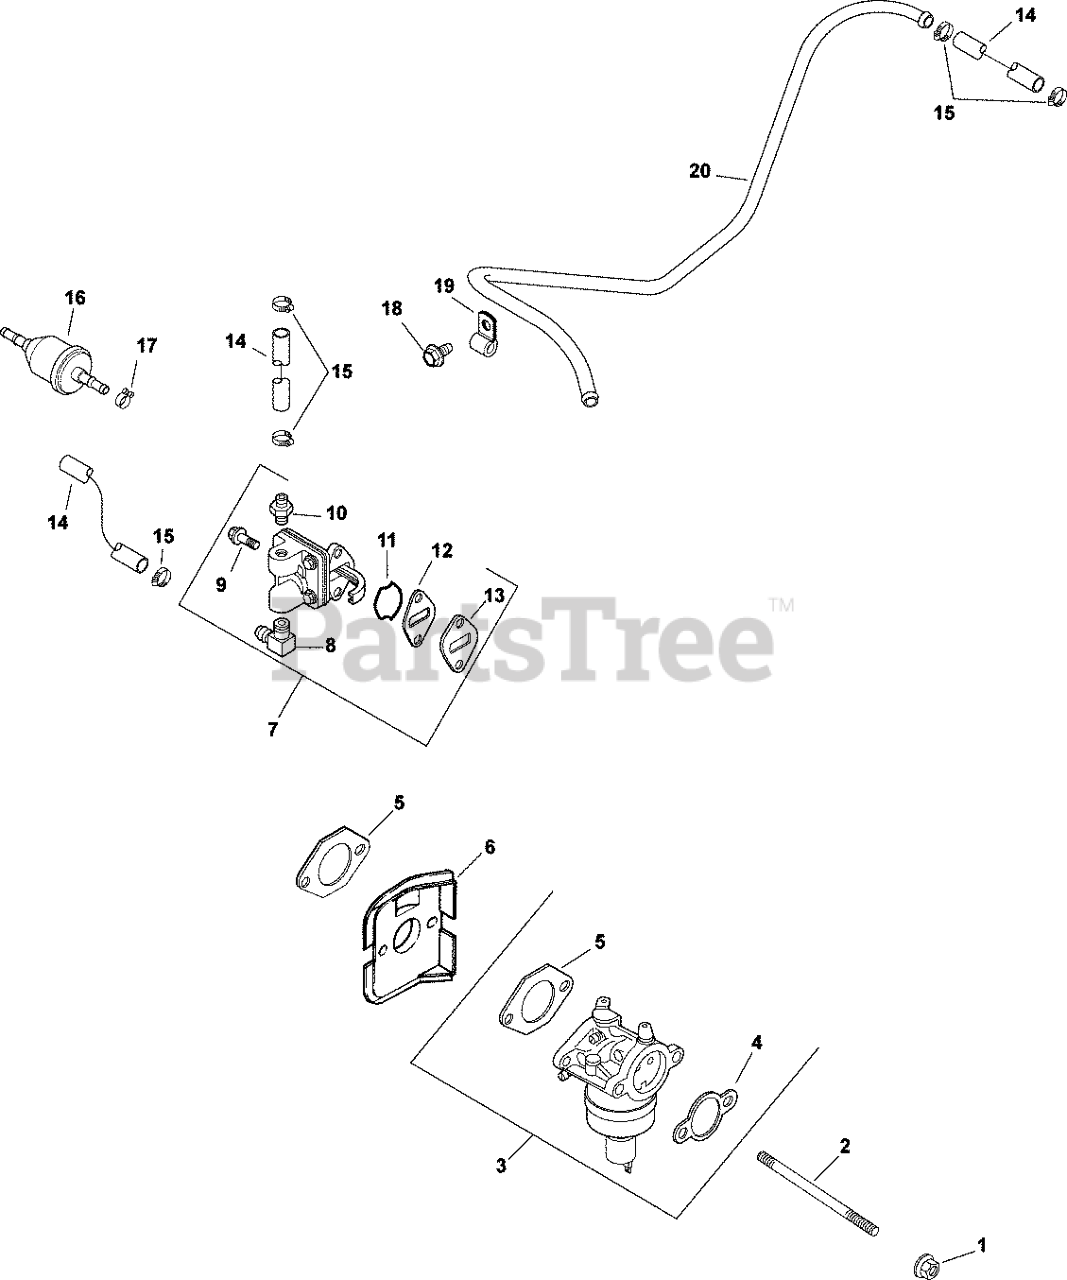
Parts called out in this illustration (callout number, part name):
1	NUT, FLG M6X1.0
2	STUD,M6X1.0X116
3	KIT, CARBURETOR w/GASKETS
4	GASKET, AIR CLEANER BASE
5	GASKET, CARBURETOR
6	DEFLECTOR, HEAT
7	KIT, FUEL PUMP
8	CONNECTOR, 90 DEG. HOSE
9	SCREW, LBD SKT M6x1.0x20-(#25086403S)
10	KIT, STRAIGHT FITTING
11	O-RING, FUEL PUMP
12	GASKET, FUEL PUMP
13	SPACER, FUEL PUMP
14	HOSE,LW PERM.FUEL 24.00"-USE 25 111 81-S
15	CLAMP, HOSE (KM)-USE 25 237 31-S
16	FILTER,FUEL 51 MICRON (FUEL PUMP)
17	CLAMP, BAND SPRING HOSE-(#2523737S)
18	SCREW, FLG THD FRM M5X.8X10
19	CLIP, TUBE & WIRING (KM)
20	LINE, FUEL
1252104-S	KIT, INLET SEAT (PRESSURE) CMD
